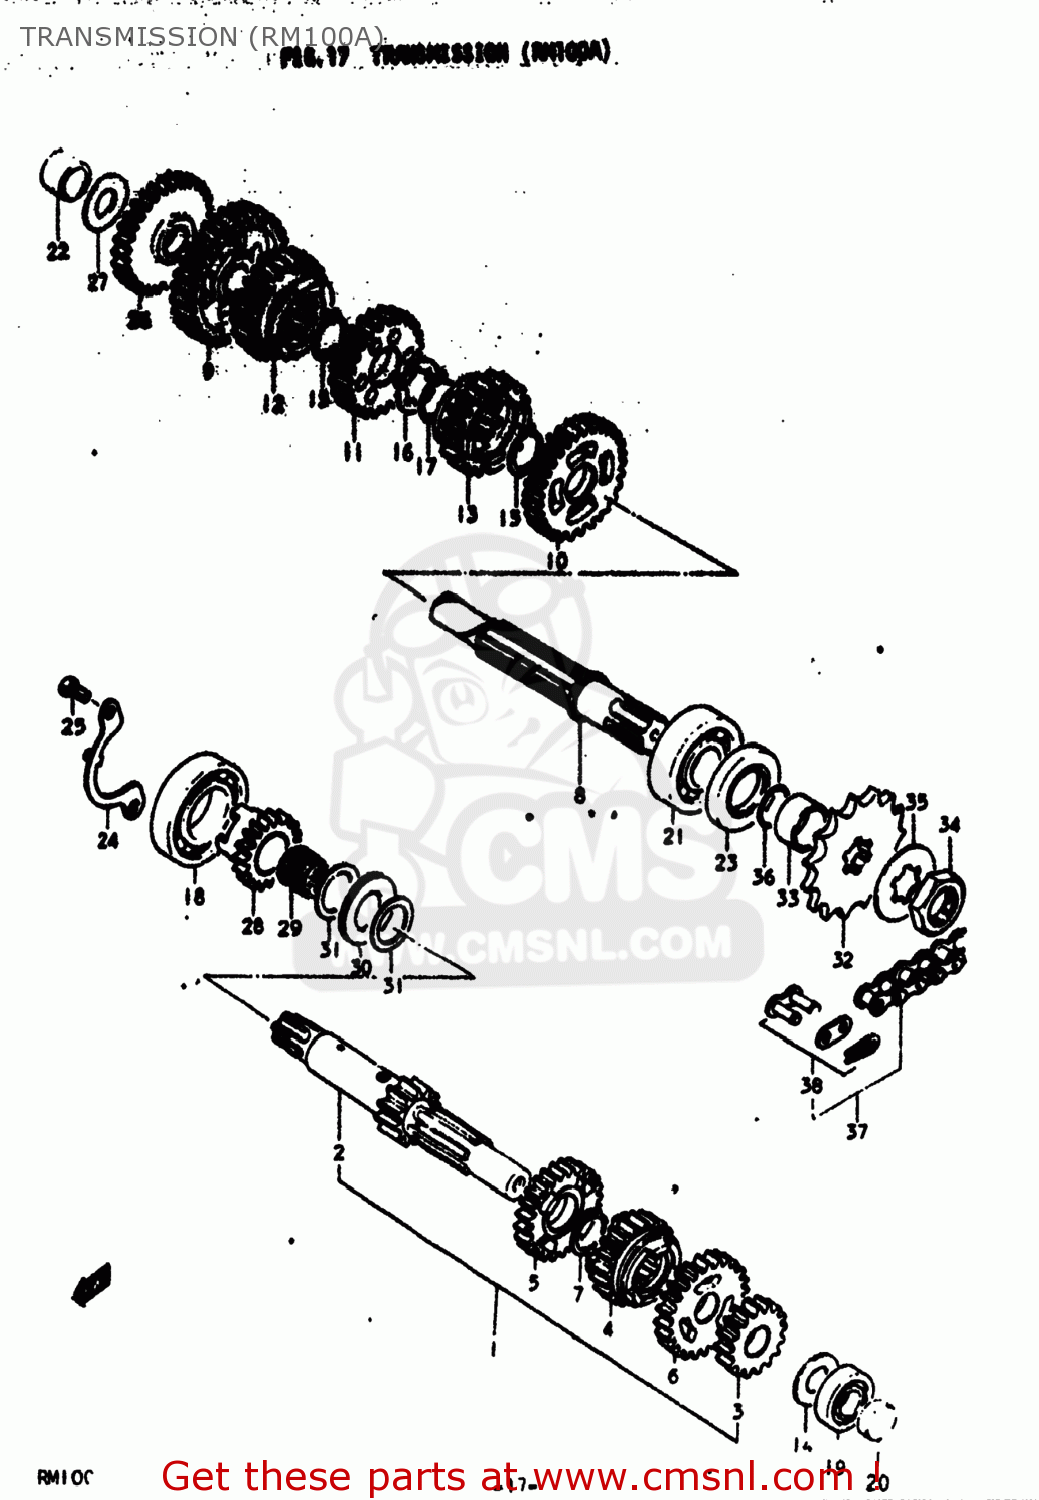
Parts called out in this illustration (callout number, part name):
1	SHAFT,COUNTER
2	SHAFT,COUNTER
3	GEAR,SECOND DRIVE
4	GEAR,THIRD DRIVE
5	GEAR,FOURTH DRIVE
6	GEAR,FIFTH DRIVE
7	CIRCLIP
8	SHAFT,DRIVE
9	GEAR,FIRST DRIVEN
10	GEAR,SECOND DRIVEN
11	GEAR,THIRD DRIVEN
12	GEAR,FOURTH DRIVEN
13	GEAR,FIFTH DRIVEN
14	WASHER
15	CIRCLIP
16	WASHER
17	CIRCLIP
18	BEARING, RH
19	BEARING
20	PLUG
21	BEARING
22	BUSH
23	OIL SEAL (25X44X7)
24	RETAINER,CNTR SHAFT BEARING
25	SCREW 6X12
26	GEAR,KICK STARTER IDLE
27	WASHER
28	GEAR,KICK STARTER DRIVE
29	BEARING(19.2X23.2X19)
30	BEARING(21X32X2.85)
31	WASHER(21X30X0.8)
32	SPROCKET,ENGINE
33	SPACER(20X25X12.5)
34	NUT
35	WASHER,LOCK
36	O RING(D:1,ID:19.5)
37	CHAIN ASSEMBLY,DRIVE
38	JOINT ASSEMBLY,CHAIN
